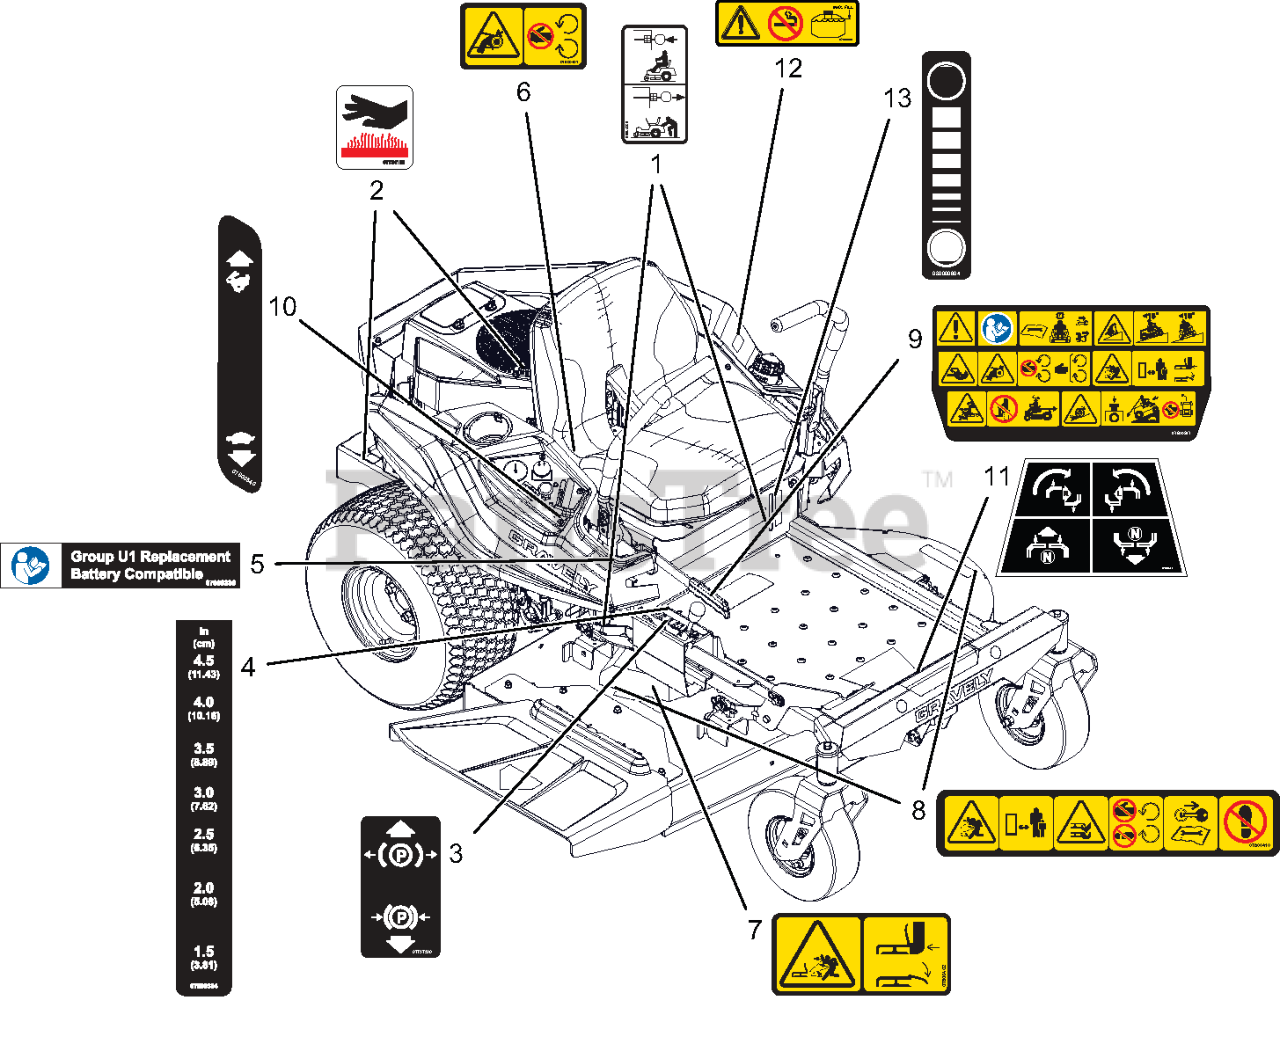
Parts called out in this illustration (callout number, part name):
1	DECAL, TRANSMISSION DISCONNECT
2	DECAL, HOT SURFACE
3	Decal, Parking Brake Lever
4	DECAL, HEIGHT OF CUT
5	DECAL, U1 BATTERY REPLACEMENT
6	DECAL, SAFETY - GUARDING
7	DECAL, SAFETY - DECK GUARDING
8	DECAL, DECK SAFETY
9	DECAL, SAFETY - DECK GUARDING
10	DECAL, DECK SAFETY
11	DECAL, MAIN SAFETY
12	DECAL, DASH DECAL
13	DECAL, FUEL LEVEL
